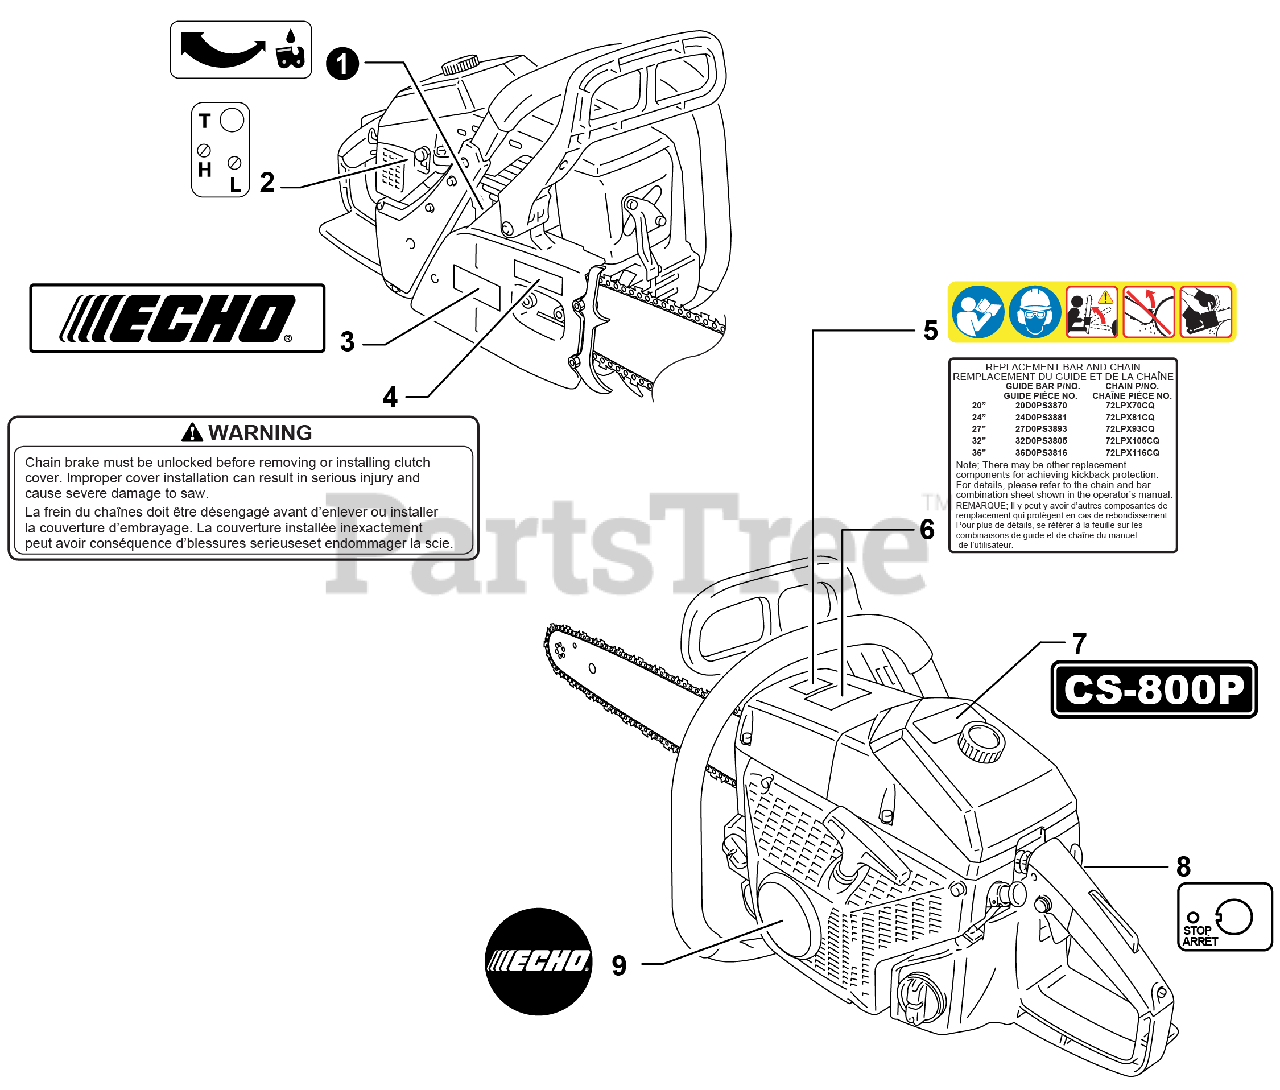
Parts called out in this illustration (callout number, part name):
1	LABEL, OILER
2	LABEL, CARBURETOR
3	LABEL, ECHO
4	LABEL, WARNING
5	LABEL, CAUTION
6	LABEL, BAR & CHAIN
7	LABEL, CS-800P
8	LABEL, STOP
9	LABEL, ECHO
